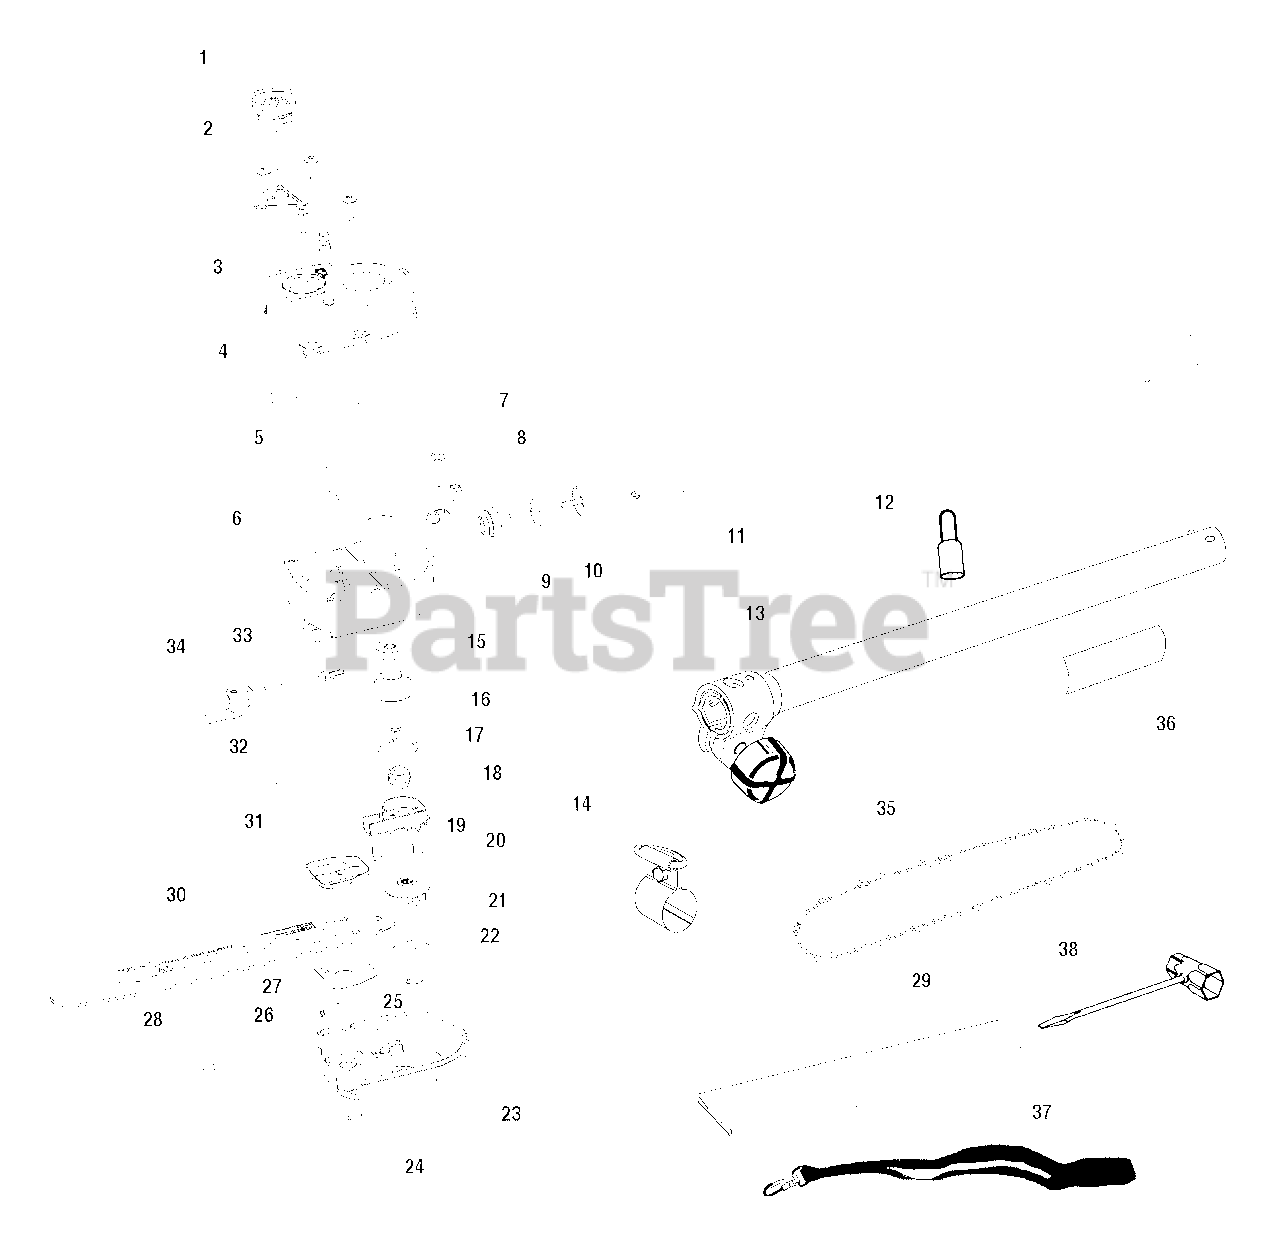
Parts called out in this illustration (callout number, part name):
1	OIL CAP
3	OIL TANK COVER ASSEMBLY
4	OIL COVER GASKET
5	PICK UP TUBE ASSEMBLY
6	GEAR HOUSING
7	SCREW (1/4-20 X 1 in.)
8	SCREW (10-24 X 1/2 in.)
9	PINION ASSEMBLY
10	RETAINING RING
11	LOWER DRIVE SHAFT ASSEMBLY
12	HANGER CAP
13	INTERMEDIATE DRIVESHAFT ASSEMBLY
14	STRAP HANGER
15	GEAR ASSEMBLY
16	RETAINING RING
17	WORM GEAR
18	OIL PUMP HOUSING
19	TRUSS HEAD SCREW
20	SPROCKET
21	CUPPED WASHER
23	BAR CLAMP ASSEMBLY
24	HEX NUT (5/16-18)
25	GUIDE BAR ADJUSTMENT PIN
26	RETAINING RING
27	GUIDE BAR PLATE
28	GUIDE BAR ADJUSTMENT SCREW
29	SCABBARD
30	GUIDE BAR
31	BAR PAD PLATE
32	OIL PUMP CAM PIN
33	GEAR AND PLUNGER
34	OIL PUMP SEAL
35	CHAIN
36	WARNING LABEL
37	HARNESS
38	COMBINATION WRENCH
39	8 oz. BOTTLE OF OIL
